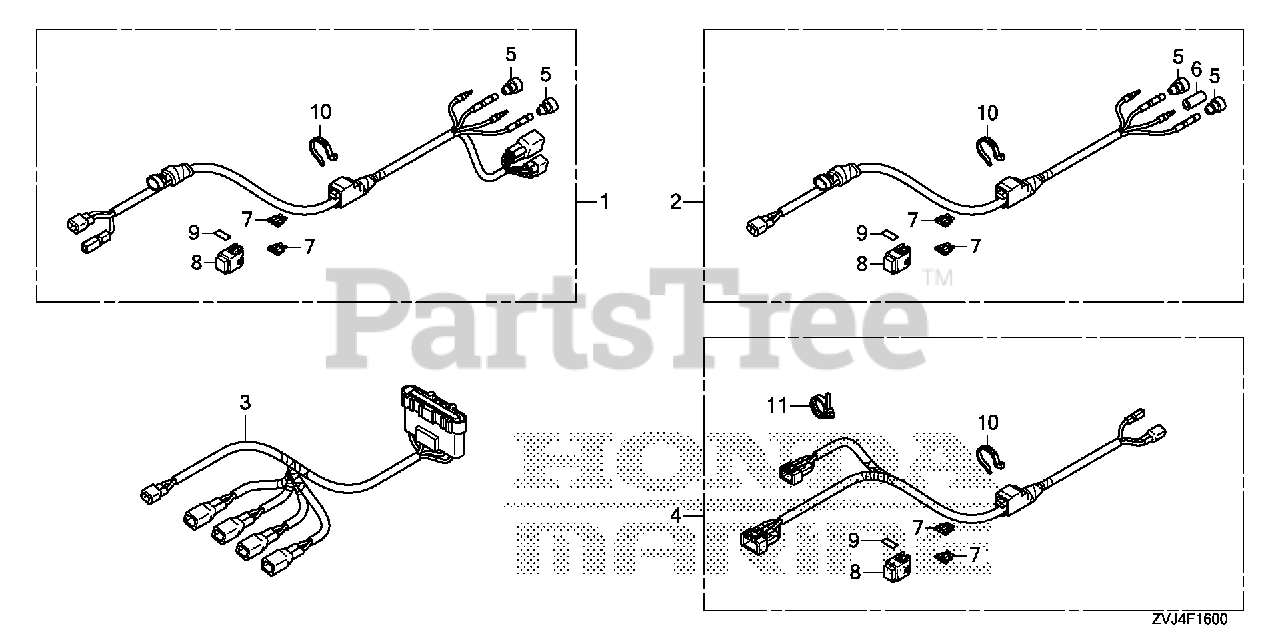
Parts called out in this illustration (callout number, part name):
1	CABLE ASSY., DIODE
2	CABLE ASSY., DIODE (TWIN)
3	SUB-CABLE ASSY., DIODE
4	CABLE ASSY., RELAY
5	PLUG, CONNECTOR (INNER)
6	PLUG, CONNECTOR (OUTER)
7	FUSE, BLADE (3A)
8	COVER ASSY., FUSE (3A)
9	LABEL, FUSE (3A)
10	HOLDER, CONNECTOR (128.6MM) (NATURAL)
11	CLIP, HARNESS BAND (155.3MM) (BLACK)
